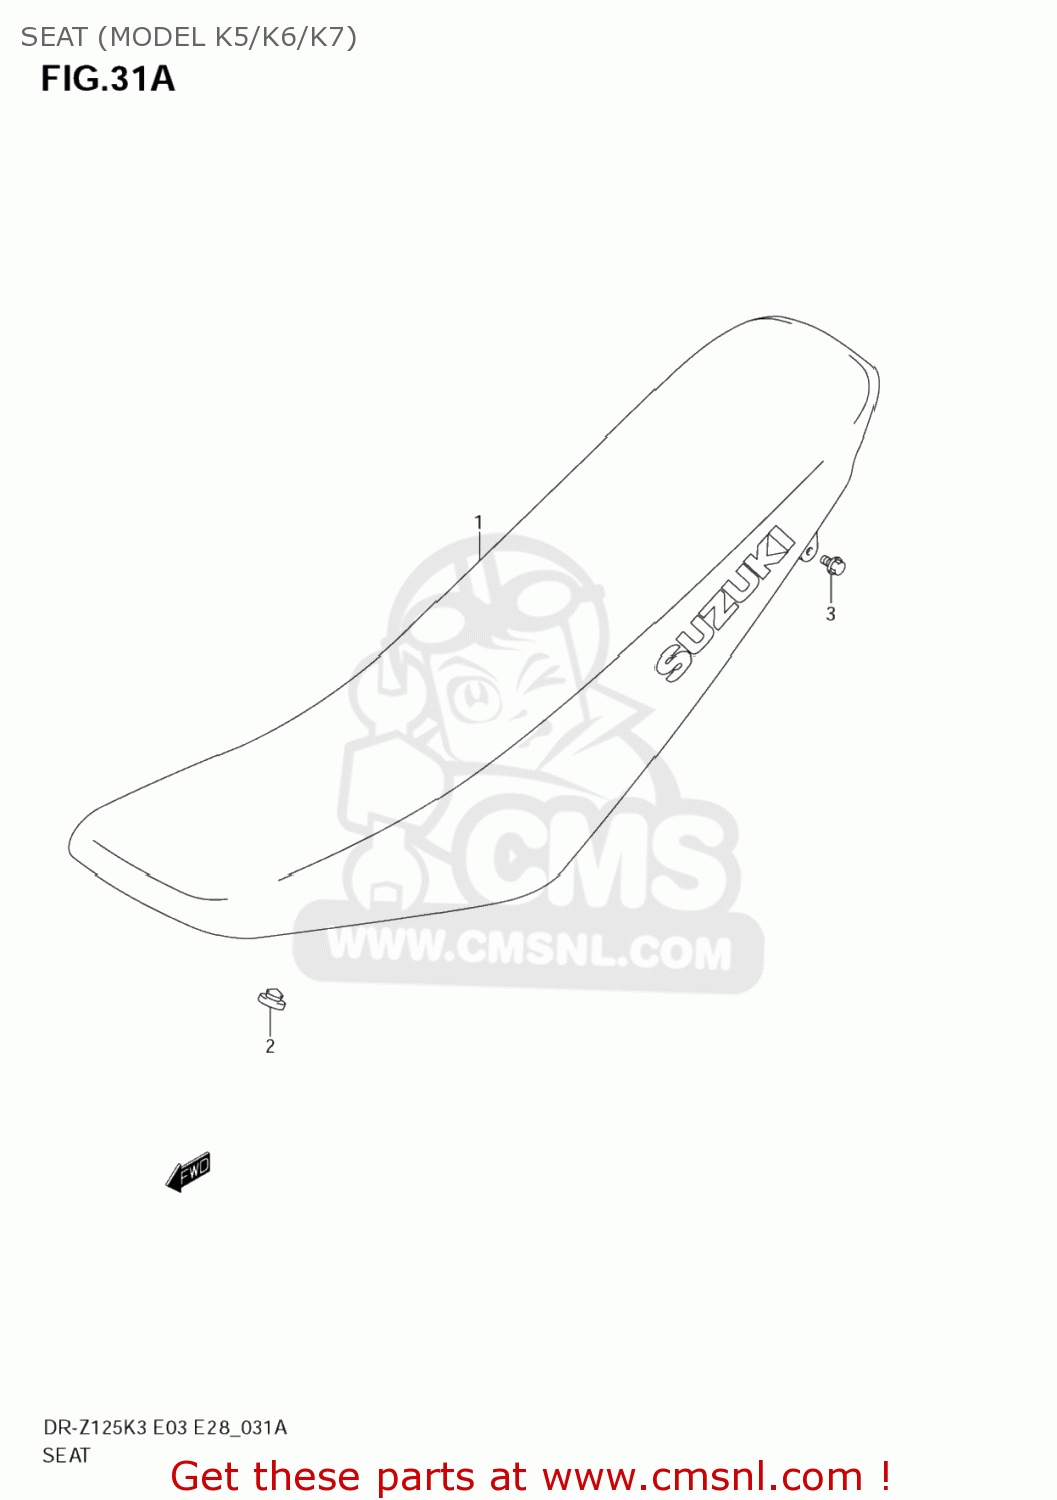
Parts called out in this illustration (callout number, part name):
1	SEAT ASSY
2	CUSHION
3	BOLT
